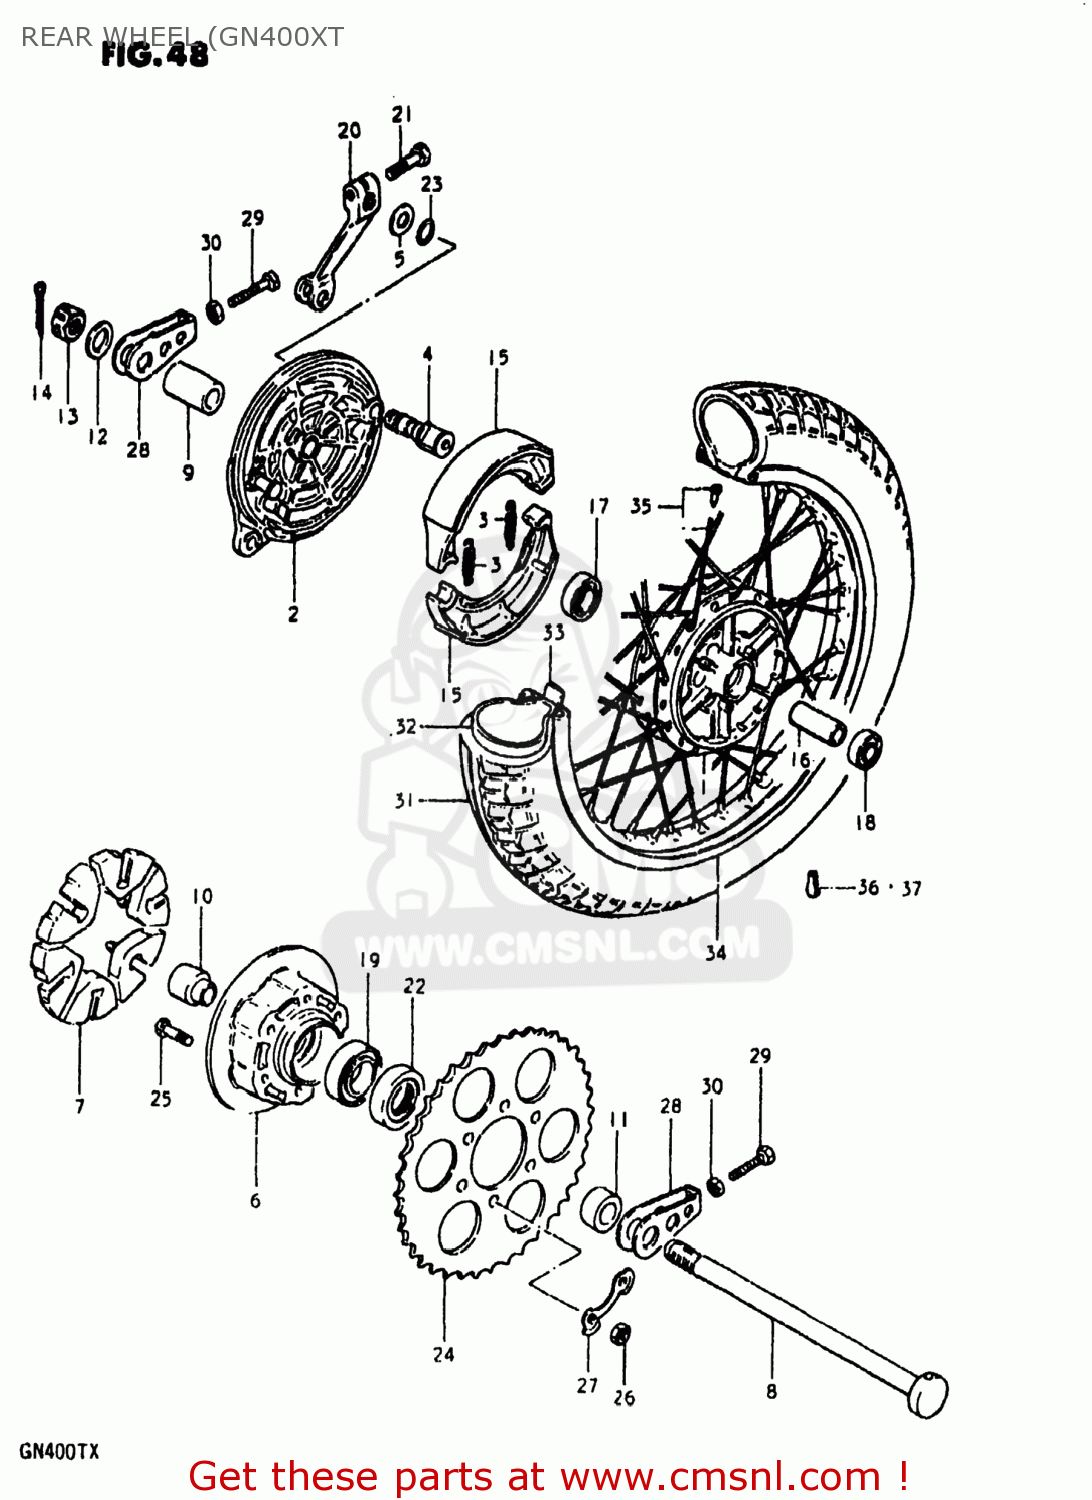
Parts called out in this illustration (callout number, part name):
1	DRUM,REAR HUB
2	PANEL,REAR HUB
3	SPRING
4	CAM,FRONT BRAKE
5	WASHER (15X24X1.6)
6	DRUM,REAR SPROCKET MOUNT
7	ABSORBER,RR HUB SHOCK
8	AXLE,REAR
9	SPACER (17.5X28X49.8)
10	SPACER,REAR HUB BEARING
11	SPACER(17X30.5X22.3)
12	WASHER (17X30X3.2)
13	NUT
14	PIN,COTTER
15	SHOE,BRAKE
16	SPACER (17.6X24X57)
17	BEARING
18	BEARING
19	BEARING
20	LEVER,RR BRAKE CAM
21	BOLT
22	SEAL,OIL(30.5X52X8)
23	O-RING,BOSS
24	SPROCKET,REAR (NT:37)
25	BOLT
26	NUT
27	WASHER
28	ADJUSTER,CHAIN
29	BOLT 8X50
30	NUT
